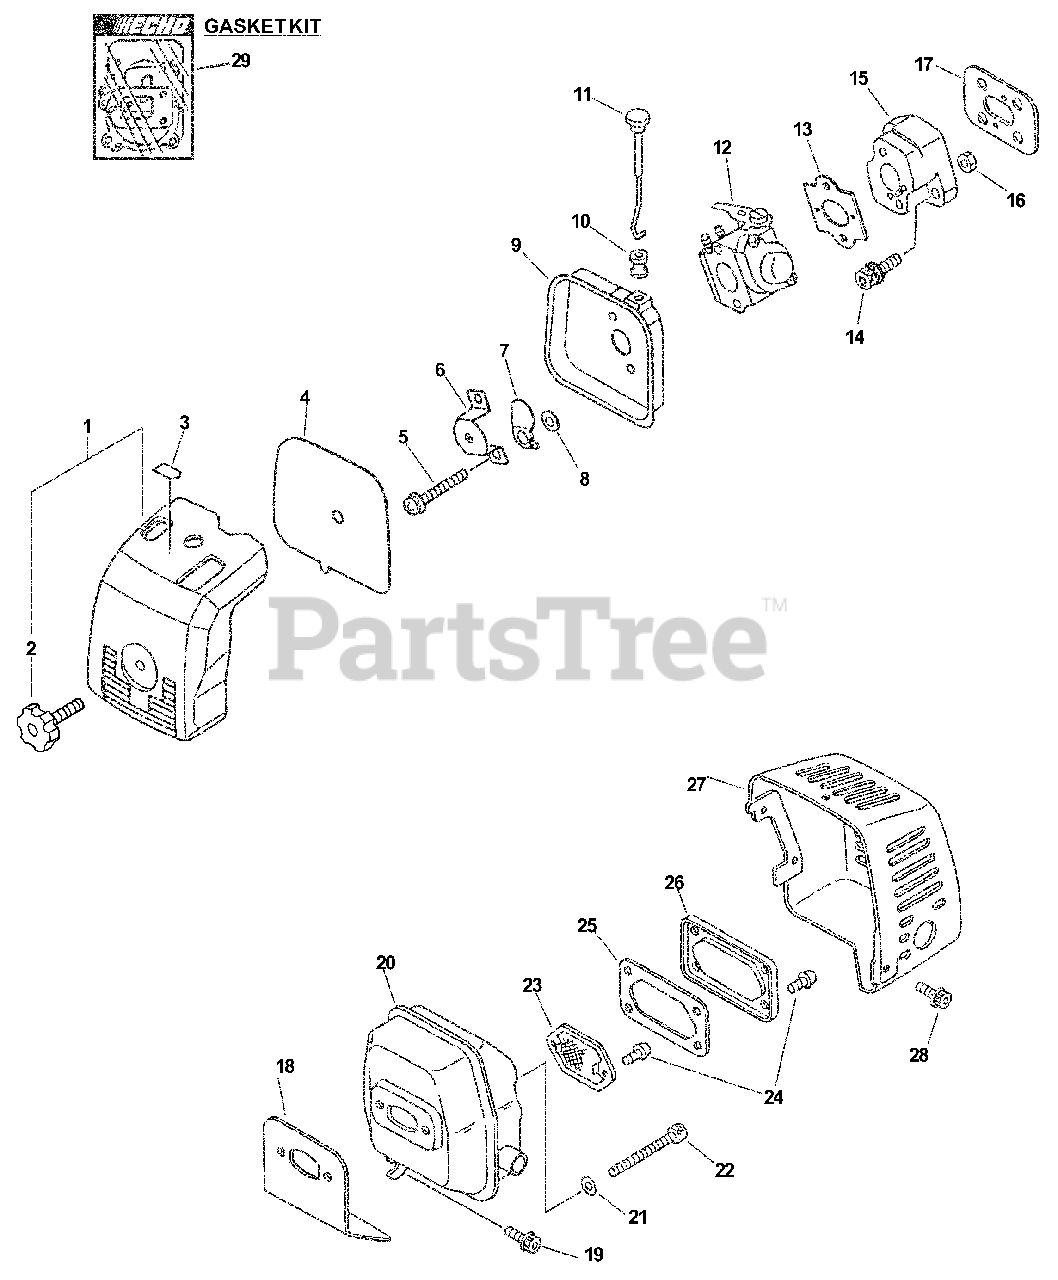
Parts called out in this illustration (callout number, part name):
1	AIR FILTER COVER ASSY
2	THUMBSCREW
3	LABEL - CHOKE
4	FILTER, AIR - HEAVY DUTY
5	SCREW - 5X57
6	PLATE, PREVENT
7	SHUTTER, CHOKE
8	WASHER - 5
9	CASE, AIR FILTER
11	ROD, CHOKE
12	CARBURETOR WT-418B
13	GASKET, INTAKE
14	SCREW - 5X25
15	INSULATOR, INTAKE
17	GASKET, INTAKE
18	GASKET, EXHAUST
19	SCREW - 5X12
20	MUFFLER
21	WASHER - 5
22	SCREW - 5X60
23	SCREEN, SPARK ARRESTOR
24	SCREW - 4X10
25	GASKET, EXHAUST
26	GUIDE, EXHAUST
27	COVER, MUFFLER
28	SCREW - 5X14
29	GASKET KIT
